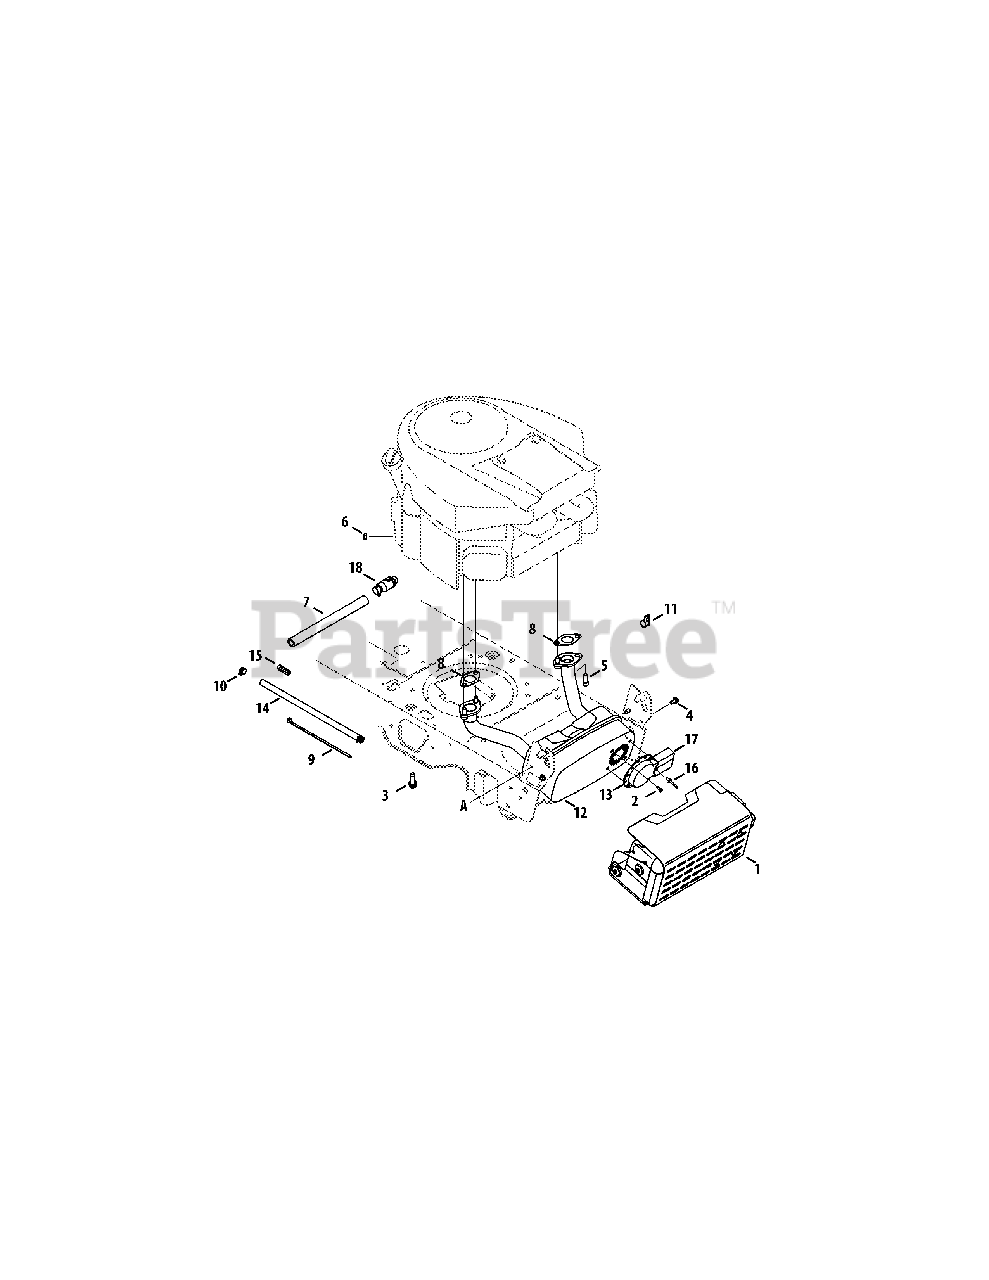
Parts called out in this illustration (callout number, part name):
1	Shield Ass’y, Muffler
2	Screw, Ab, #8-18, 0.500,
3	Screw, Self-tapping, 3/8-16, 1.000,
4	Screw, Self-tapping, 1/4-20, 0.500,
5	Screw, Socket Head, 5/16-18, .750
6	Nut, Sems, 1/4-20
7	Hose, Extension, Oil Drain
8	Gasket, Exhaust, Kohler
8	Gasket, Exhaust, Kawasaki
9	Cable, Tie, 3/16 x .05 x 7.4
10	Clamp, Hose, .490 Dia.
11	Clamp, 9/16 Dia.
12	Muffler, Kohler
12	Muffler, Kawasaki Twin
13	Deflector, Muffler
14	Hose, Fuel, Low Permeation, 1/4
15	Hose, Vent
16	Rivet, Pop, .188 Dia x .300
17	Deflector, Muffler, Long
18	Drain, Oil
